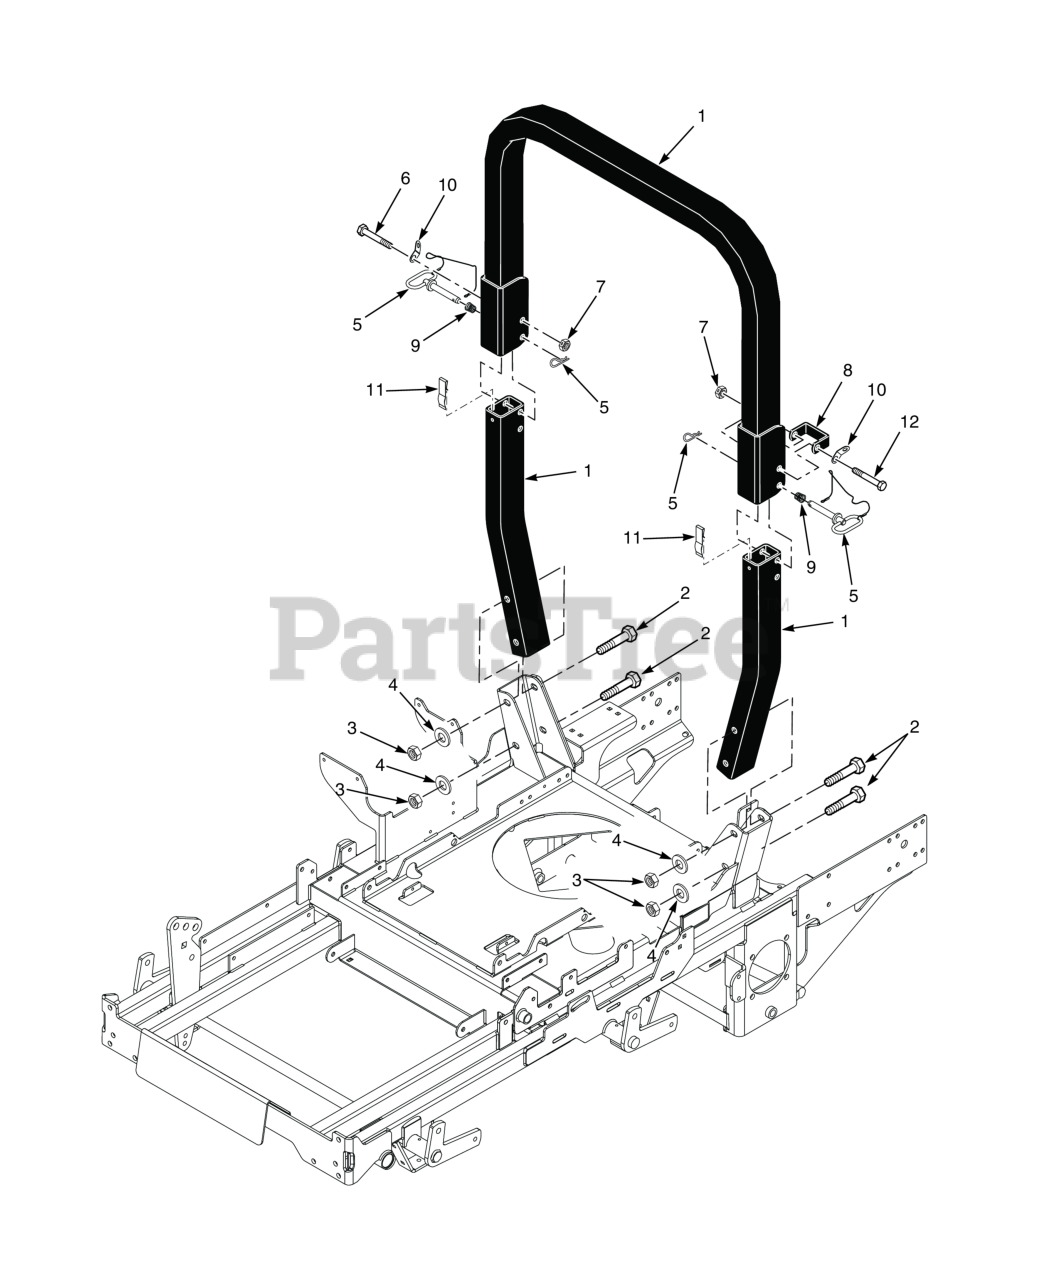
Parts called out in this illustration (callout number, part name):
1	STT, ROPS
2	Bolt, Hex Head 1/2-13 x 4-1/4"
3	Locknut, Hex 1/2-13 Center Lock
4	Flat Washer, 1/2 (.562 x 1.375 x .109)
5	Pin Assembly, ROPS Hinge
6	Bolt, Hex Head, 1/2-13 x 3-1/4"
7	HEX LOCKNUT, ELASTIC STOP, 1/2-13
8	Stop, ROPS
9	Spring, ROPS
10	Clip, ROPS
11	Spring, ROPS Anti-Rattle
12	Bolt, Hex Head 1/2-13 x 3-3/4"
